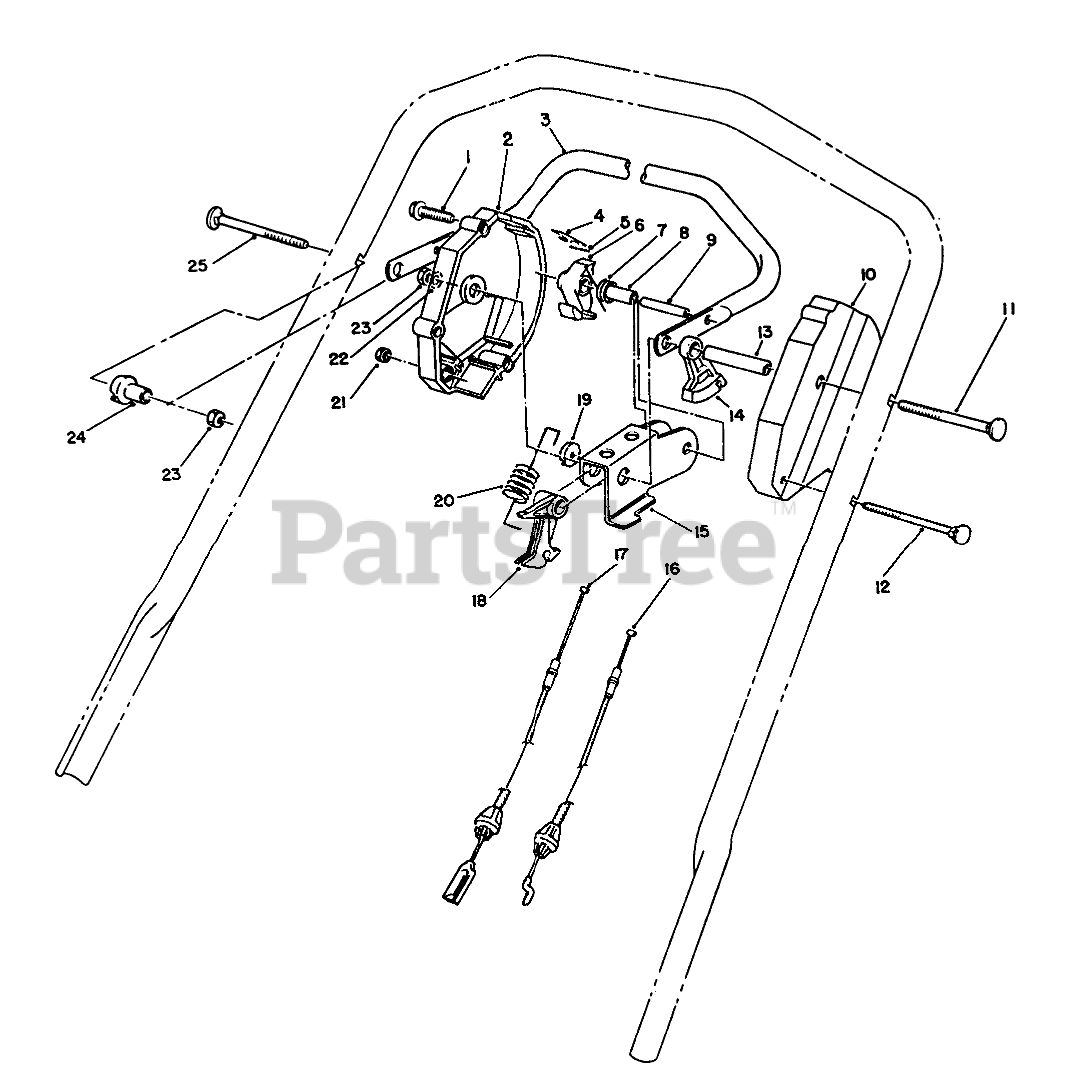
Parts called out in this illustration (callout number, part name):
1	SCREW-HWHTF
2	Housing-Control
3	Bar-Control
4	SPRING-LEAF
5	PIN-INSERT
6	HOOK-CONTROL
7	SPRING-TORSION
8	SPACER
9	PIN-ROLL, SLOTTED
10	HOUSING-CONTROL, LH
11	Screw-Handle
12	HANDLE SCREW
13	TUBING-SPACER
14	LEVER-TRACTION
15	ROCKER
16	TRACTION CABLE
16	Cable-Traction
17	BBC CABLE ASSEMBLY
17	Cable-BBC
18	LEVER-CABLE
19	WASHER-NYLON
20	SPRING-DETENT
21	NUT-HEX
22	WASHER-PLAIN
23	NUT-LOCK, NI
24	SPACER-SUPPORT
25	SCREW-HANDLE
